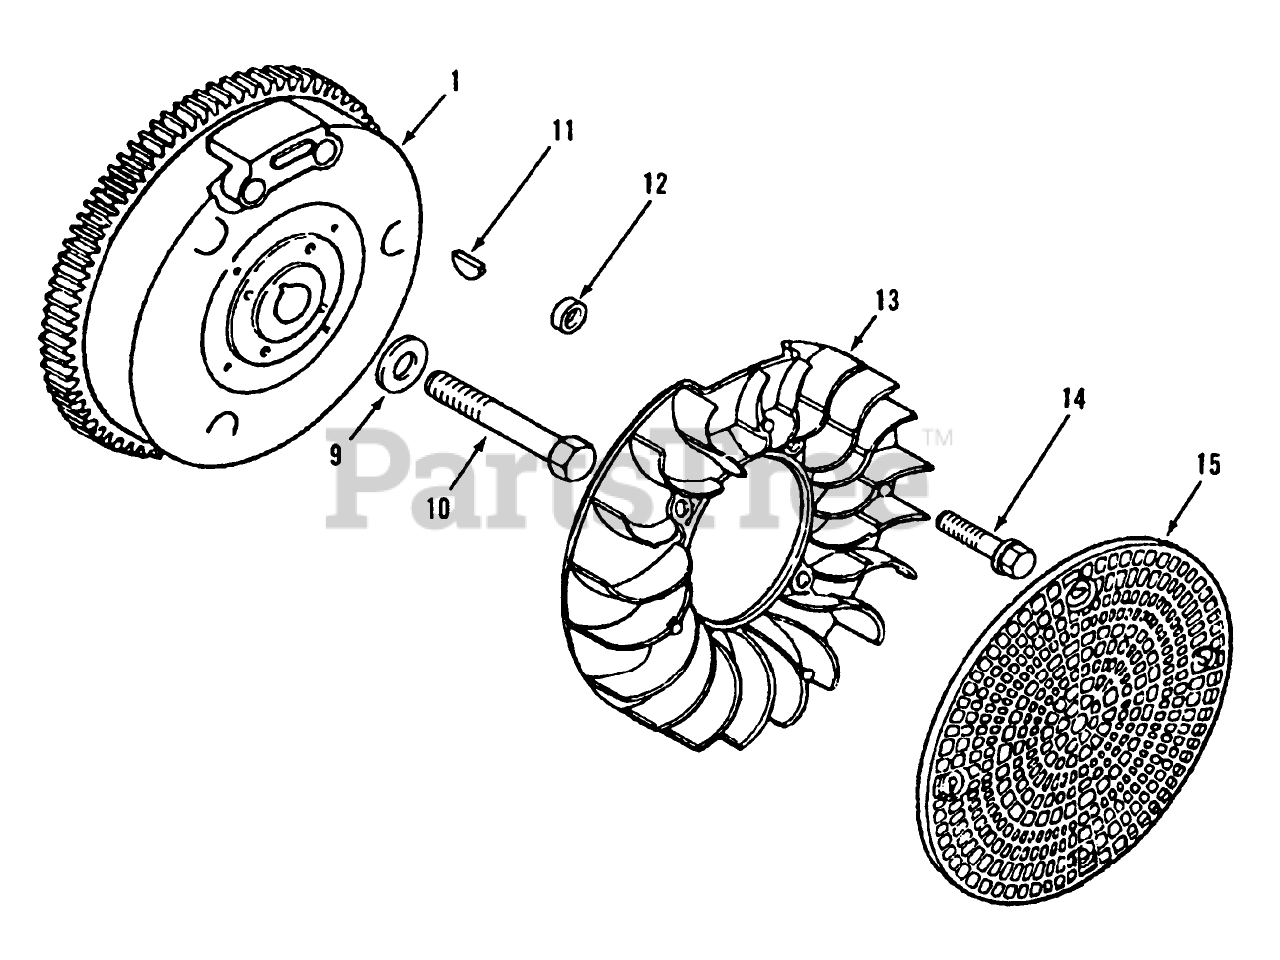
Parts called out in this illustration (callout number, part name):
1	KOHLER 47-025-60
1	KOHLER 47-025-53
9	KOHLER 52-114-02
10	KOHLER 25-086-24
11	KOHLER X-46-3
12	KOHLER 25-089-02
13	KOHLER 25-157-01
14	KOHLER 25-086-21
15	KOHLER 25-162-01
